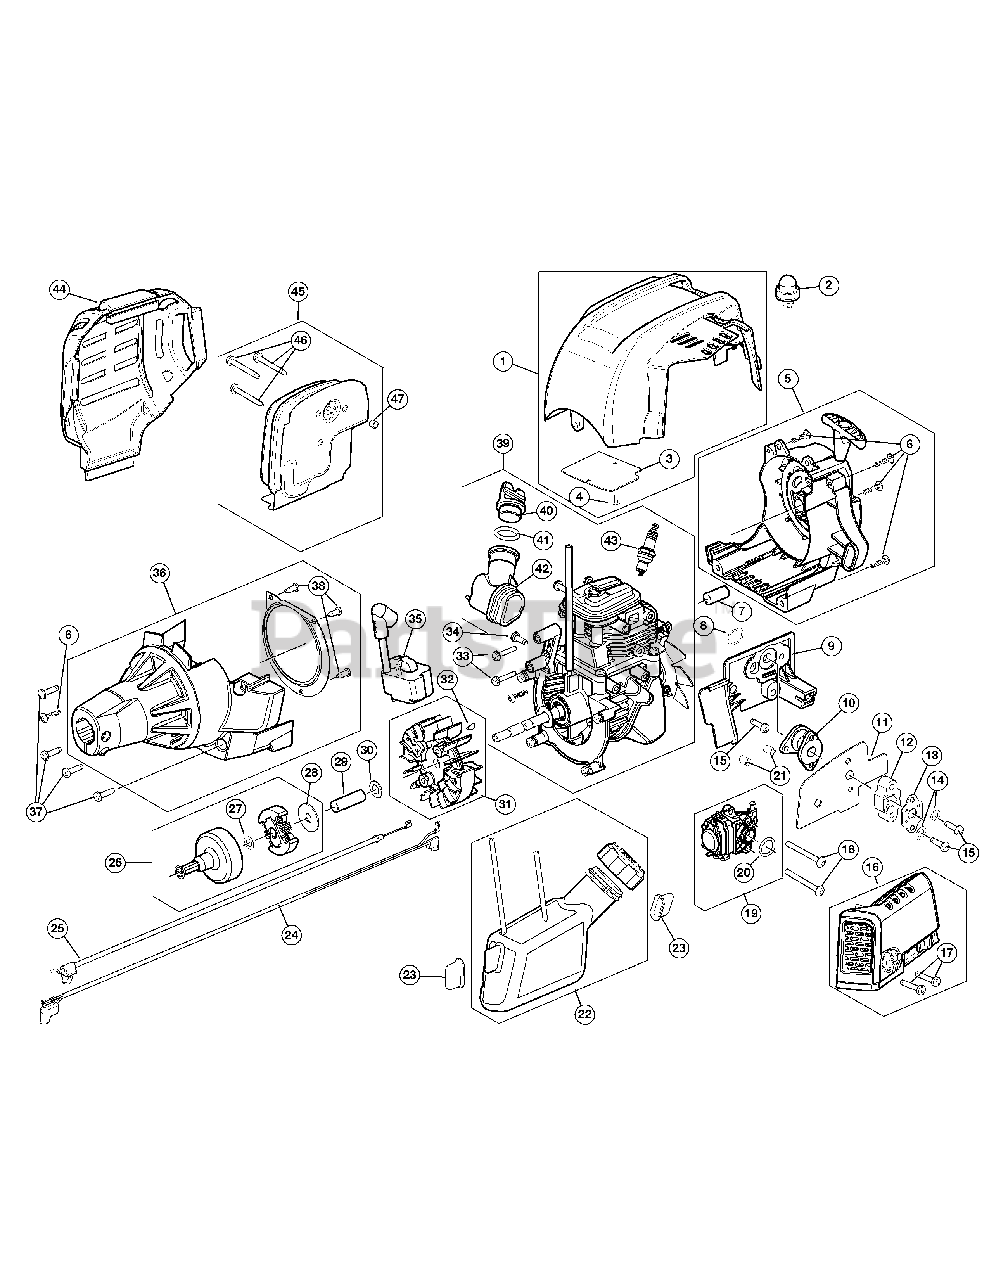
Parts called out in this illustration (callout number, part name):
1	Top Housing Assembly
2	Air Purge Primer
3	Top Cover Gasket
5	Starter Housing Assembly
7	Electric Start Adapter
9	Intake Port
10	Boot Assembly
11	Carburetor Gasket
12	Insulator
13	Insulator Gasket
15	Screw
16	Aircleaner Assembly
19	Carburetor Assembly
21	Aircleaner Spacer
22	Fuel Tank Assembly
23	Fuel Tank Pad
24	Lead Wire
25	Thottle Cable
26	Clutch Assembly
27	Thrust Washer
28	Clutch Washer
29	Power Shaft Spacer
30	Thrust Washer
31	Flywheel Assembly
35	Module Assembly
36	Clutch Cover Assembly
39	Shortblock Assembly
40	Oil Fill Plug
42	Oil Fill Tube
43	Spark Plug
44	Muffler Housing
45	Muffler Assembly
46	Screw
47	Aircleaner Spacer
